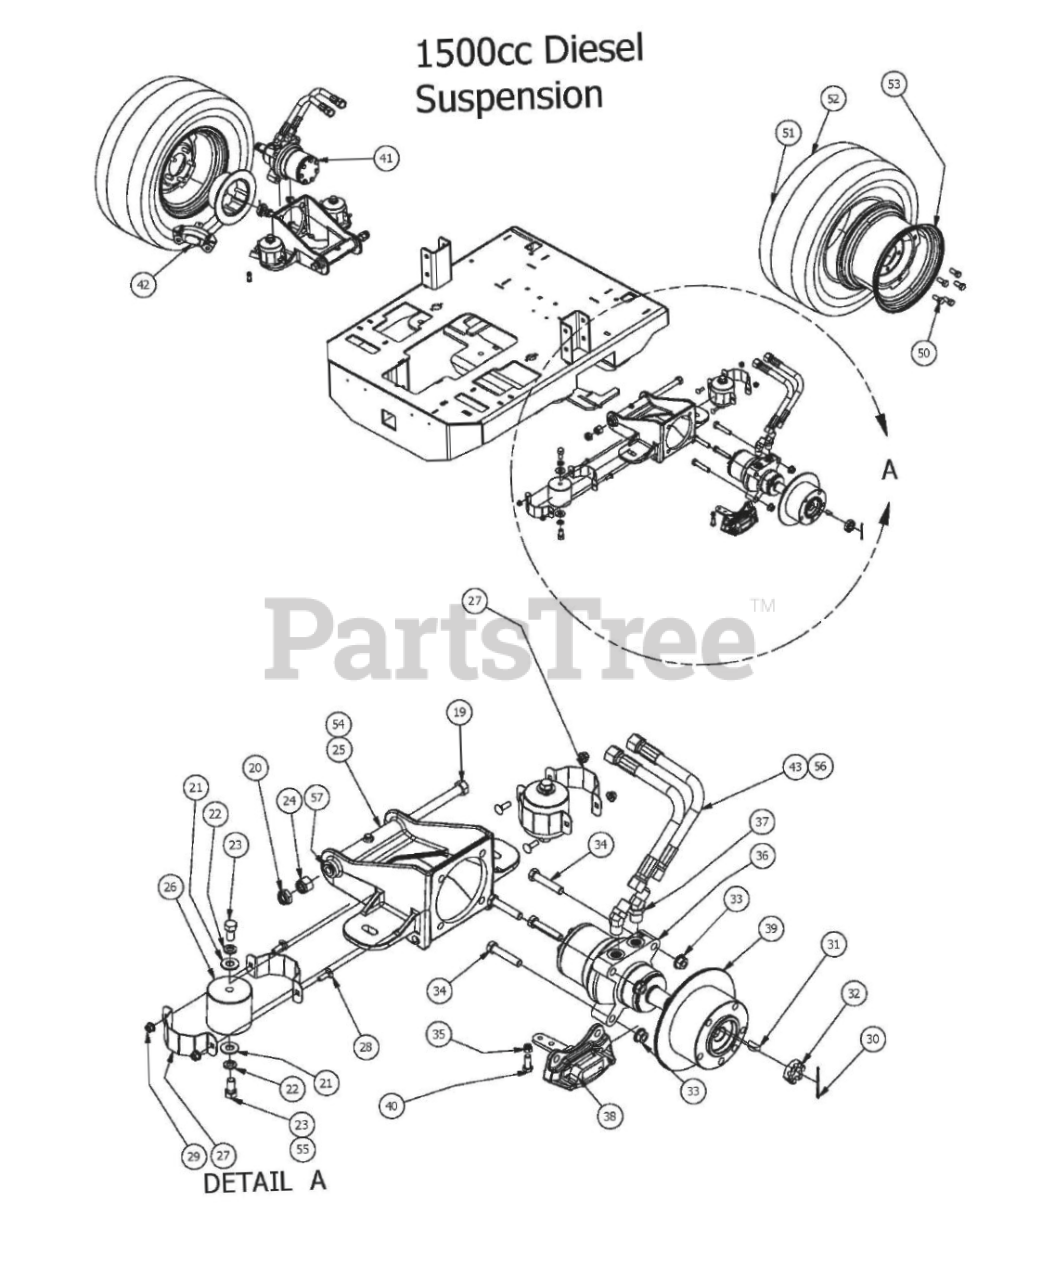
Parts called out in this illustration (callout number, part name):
1	Diesel Back Pump Cover 2008 Bottom
2	Back Cover Hinge Bracket
3	Diesel Back Pump Cover 2008 Top
4	Diesel Hood 4 Cyl
5	5/16" x 1" Carriage Bolt
6	360 ID Plastic Washer
7	1/4" x 5/8" BS C/S 18-8 SS
8	5/16-18x3/4 carriage bolt
9	5/16" Flange Nut
10	1/4 Nylock Nut
11	5/8 Round Insert
12	5/16" x 1" Bolt
13	5/16-18 Nylock Insert Locknut
14	5/16" Knob
15	5/16" x 1 1/4" Carriage Bolt
16	1/4" x 1 1/2" Self Tapping Screw
17	1/4" Flat Washer
18	8" Rubber Bumper
19	5/8"x10" Hex Bolt (Grade8)
20	5/8" Nylock (1/2 Jam)
21	1/2" Washer (Grade 8)
22	1/2" Lock Washer
23	1/2" x 1" Hex Bolt
24	5/8 Std NC Nylock Nut
25	60 Suspension kit Wheel Motor
26	Vibration Mount-Blue Dot
27	Isolator Band Clamp
28	5/16" x 1" Carriage Bolt
29	5/16" Nylon Flange Nut
30	1/8x2-1/4 cotter pin Zinc
31	Woodruff Key
32	1" Castle Nut for Wheel Motor
33	1/2" Flange Nut
34	1/2" x 2 1/2" Hex Bolt.
35	5/16-18 Nylock Insert Locknut
36	18cc Parker Wheel Motor- Right
37	45 Degree Wheel Motor Fitting -6802-10-10
38	XP/AOS Right Brake Caliper
39	Brake Disk
40	3/8" x 1" Hex Bolt
41	18cc Parker Wheel Motor- Left
42	XP/AOS Left Brake Caliper
43	26" Hose Assembly with Adaptors
44	5/8" x 2 1/2" Grade 5 Hex Bolt (Coarse)
45	5/8 Std NC Nylock Nut
46	5 V Idler Pulley - BCVI-81
47	5/8" x 1/" Collar W/One Set Screw
48	Steel Pump Cover Latch
49	10-24 X 5/8 BS Button Head Bolt
50	1/2-20 x 1-1/2 Lug Bolts Zinc
51	26 x 12.00-12 Tire and Orange Wheel Assembly
52	26 x 12.00 12 Tire
53	12 x 10.5 Wheel AOS Rear
54	72 Suspension Kit Wheel Motor
55	1/2-13 1-1/4 Hex bolt Only On 60" Suspension Kit Wheel Motor
56	26" Hose Only
57	Brass Bushing
58	10-24 Nylock Locknut
